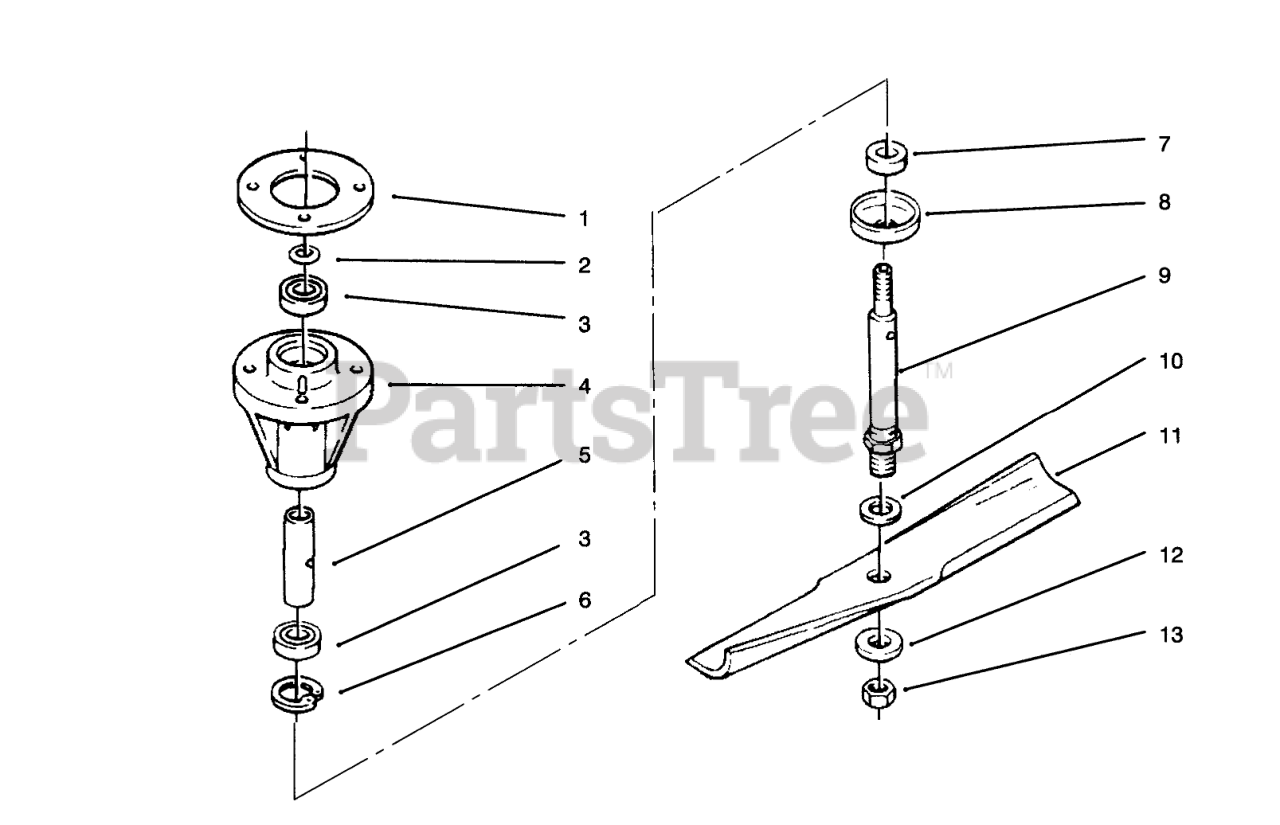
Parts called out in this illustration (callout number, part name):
1	SPACER-SPINDLE
2	O RING
3	BEARING-BALL
4	HOUSING-SPINDLE
6	RING-RETAINING
7	SPACER-BLADE
8	CUP-SPINDLE
9	SHAFT-SPINDLE
10	Washer
11	BLADE KIT (3- 79-2920)
12	WASHER-FLAT
13	Nut-Jam
